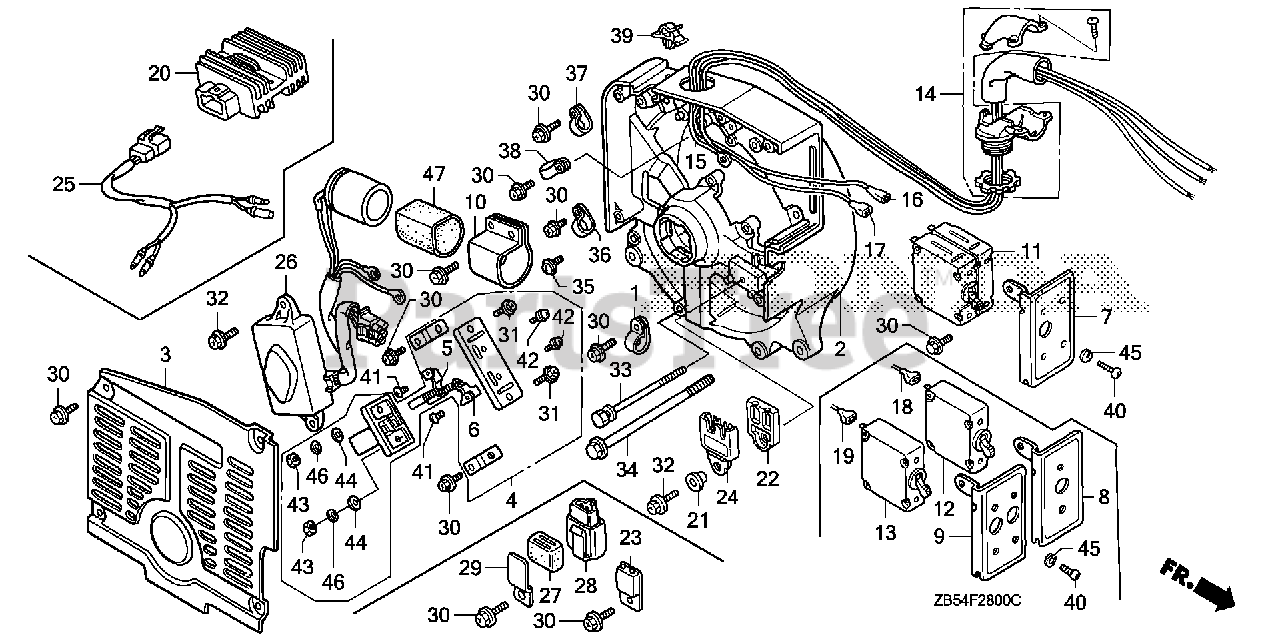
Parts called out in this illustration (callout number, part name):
1	CLAMP F, CABLE
2	HOUSING, RR.
3	COVER, GENERATOR END
4	HOLDER ASSY., BRUSH
9	BRACKET, BREAKER *NH192M* (GENTLY SILVER METALLIC)
10	HOLDER, CONDENSER
12	BREAKER, CIRCUIT (30A)
13	BREAKER, CIRCUIT (20A)
14	FITTING (NOT AVAILABLE)
15	WIRE, GROUND
18	WIRE, BREAKER (RED)
19	WIRE, BREAKER (1720MM) (RED/WHITE)
23	DIODE, D.C.
26	REGULATOR ASSY., AUTOMATIC VOLTAGE
27	SUSPENSION, TURN SIGNAL RELAY (MITSUBA)
28	RELAY, CONTROL
29	BRACKET, RELAY
30	SCREW, TAPPING (5X12) (GROUND CABLE)
31	SCREW, TAPPING (5X14)
32	SCREW, TAPPING (5X14)
33	BOLT-WASHER (5X180)
34	BOLT, FLANGE (8X190)
35	SCREW, PAN (5X12) (GROUND CABLE)
36	CLIP (10.7MM)
37	CLIP (10.7MM)
38	CLIP (15.5MM)
39	CLIP, CORD
40	SCREW, PAN (3X6)
41	SCREW, PAN (4X8)
42	SCREW-WASHER (4X16)
43	NUT, HEX. (4MM)
44	WASHER, PLAIN (4MM)
45	WASHER, SPRING (3MM)
46	WASHER, SPRING (4MM)
